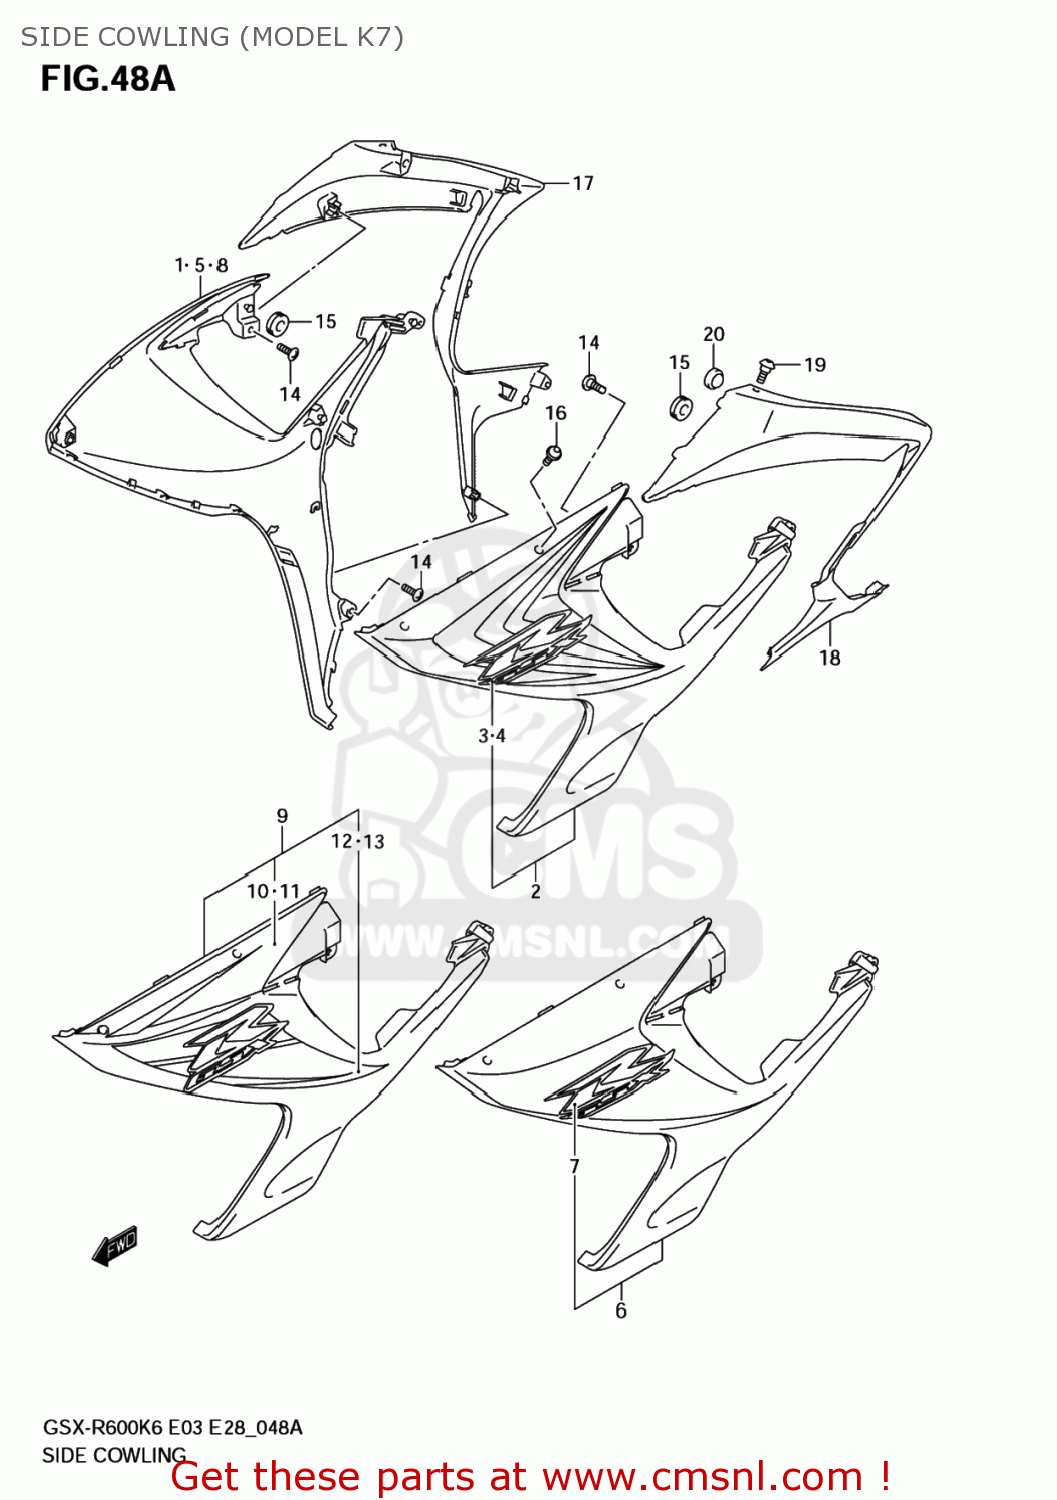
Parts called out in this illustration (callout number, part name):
1	COWLING,SIDE,R(RED)
2	COWLING,SIDE,L(RED)
3	TAPE,COWL SIDE,R
4	TAPE,COWL SIDE,L
5	COWLING,SIDE,R(BLACK)
6	COWLING,SIDE,L(BLACK)
7	EMBLEM,GSXR
8	COWLING,SIDE,R(WHITE)
9	COWLING,SIDE,L(WHITE)
10	TAPE,COWL SIDE UPR,R
11	TAPE,COWL SIDE UPR,L
12	TAPE,COWL SIDE,R
13	TAPE,COWL SIDE,L
14	SCREW
15	CUSHION
16	SCREW(5X13)
17	COVER,UNDER COWL,R
18	COVER,UNDER COWL,L
19	SCREW(5X16)
20	CUSHION
